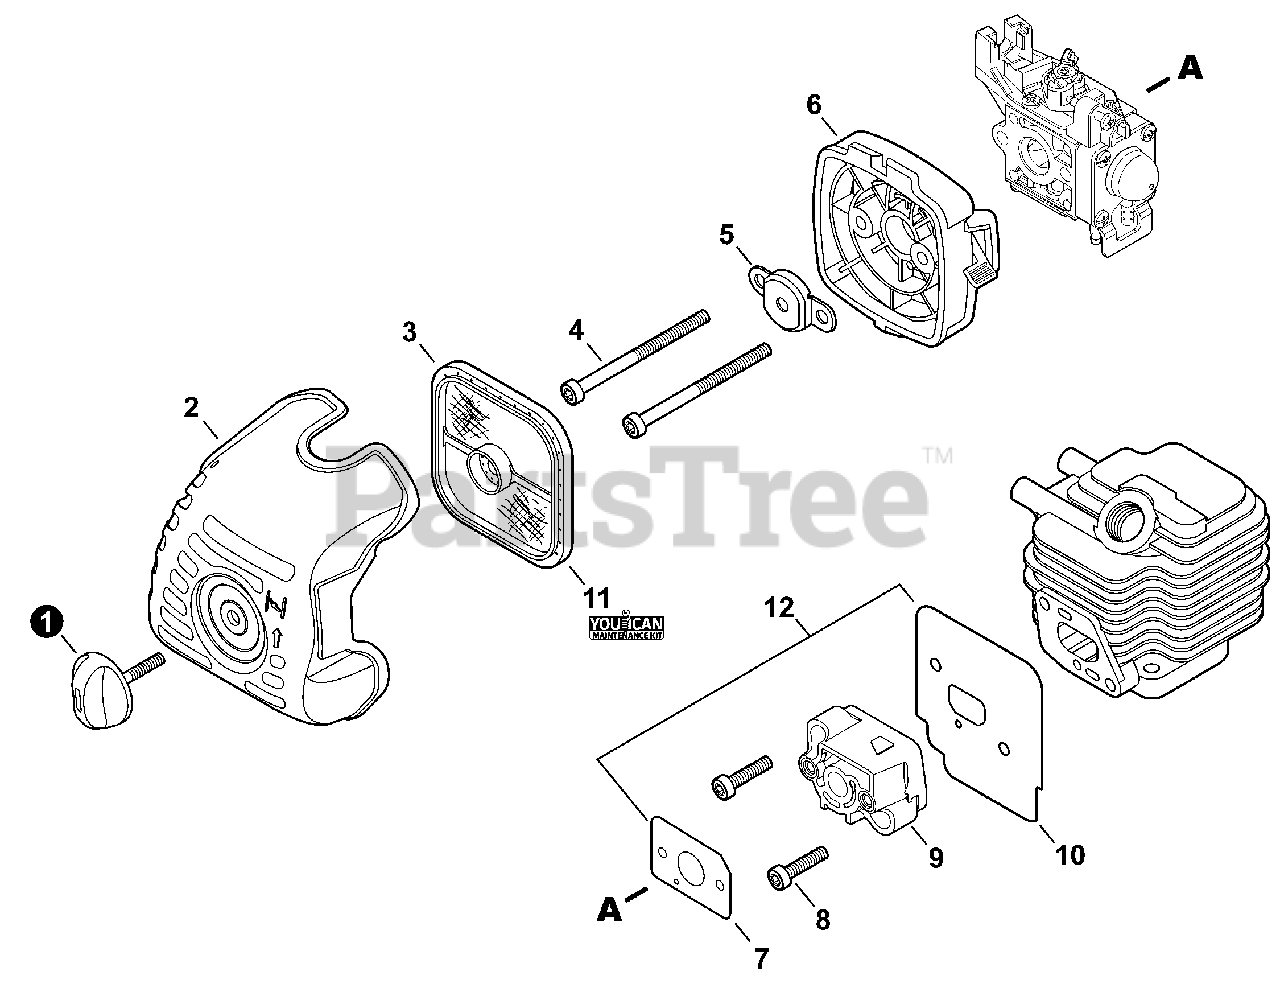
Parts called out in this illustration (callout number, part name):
1	THUMBSCREW
2	COVER, AIR FILTER
3	FILTER, AIR - DOUBLE LAYER
4	BOLT, TORX 5×55
5	PLATE, PREVENT
6	CASE ASSY, AIR FILTER
7	GASKET, INTAKE
8	BOLT, TORX 5×20
9	INSULATOR, INTAKE
10	GASKET, INTAKE
11	PLUG & FILTER KIT - YOU CAN
12	GASKET KIT
